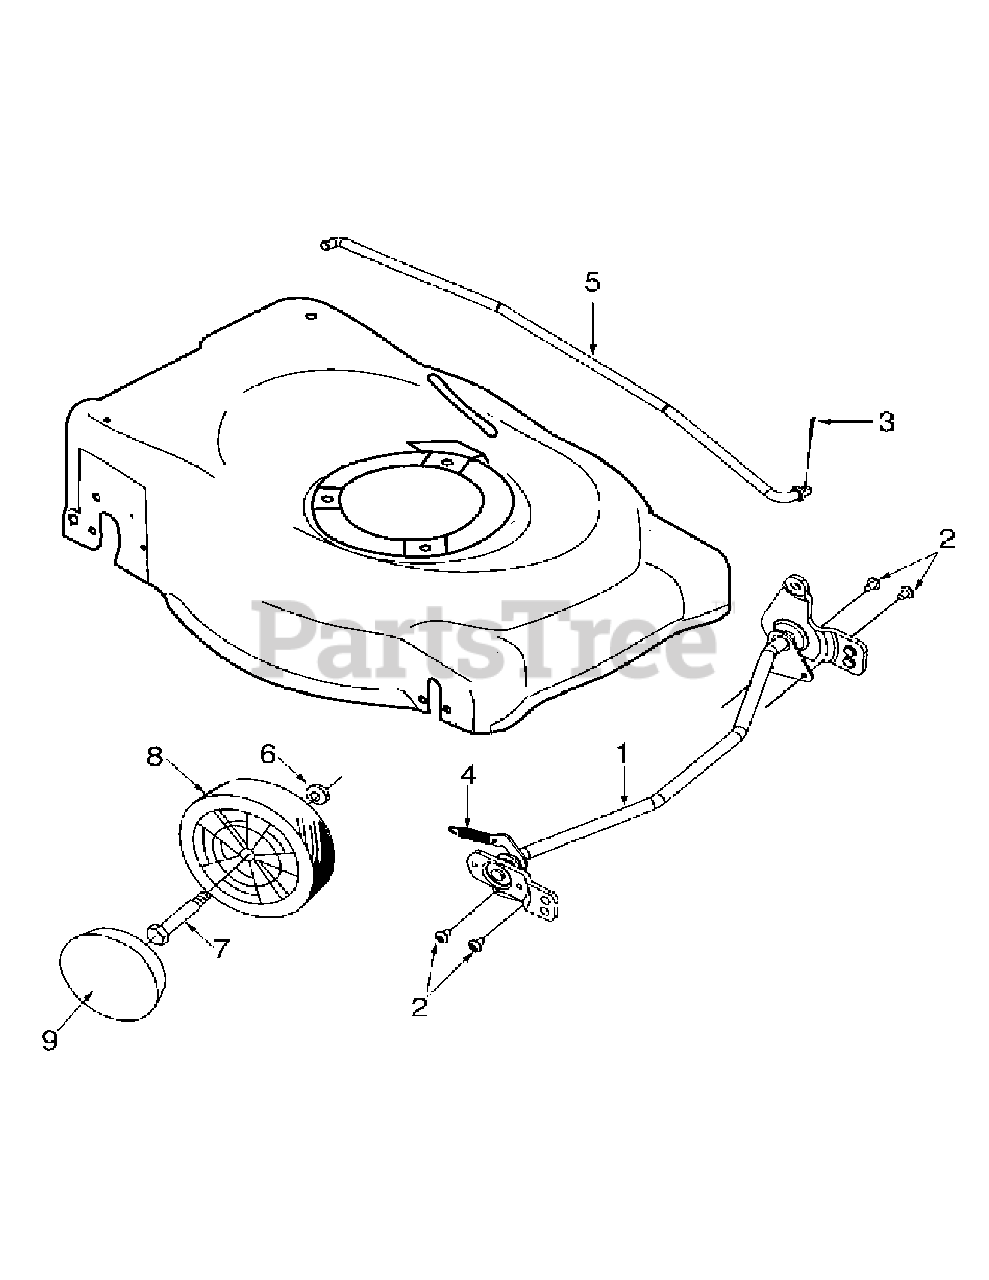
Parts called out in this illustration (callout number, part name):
2	AB Pan Scr. 1/4-14 x .50 Lg.
3	Cotter Pin .072 x 1.12 Lg.
4	Ext. Spring
5	Adj. Rod
6	Bell Washer
7	Shl. Bolt.498 x 1.445 3/8-16
8	Wheel Ass’y - Complete
9	Hub Cap (Spoke Grey)
9	Hub Cap (Euro Grey)
